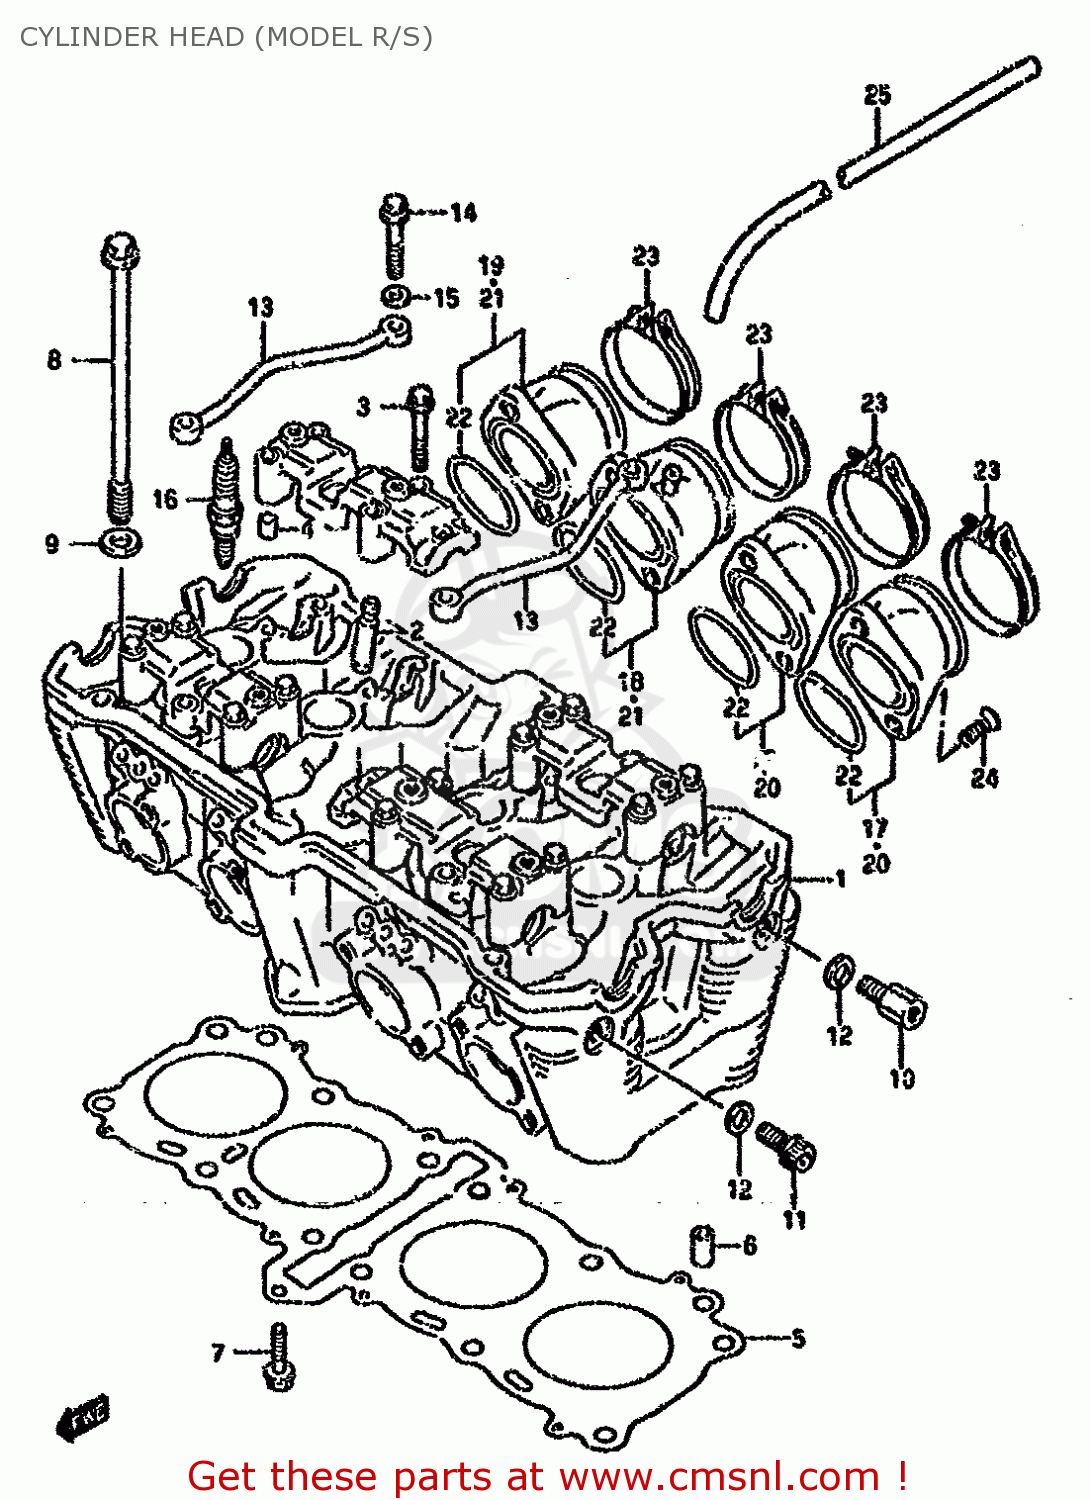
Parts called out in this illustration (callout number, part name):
1	HEAD ASSEMBLY,CYLINDER
2	GUIDE,VALVE
3	BOLT(6X45)
4	PIN(6.2X8X11)
5	GASKET,CYLINDER HEAD
6	PIN
7	BOLT
8	BOLT(10X160)
9	WASHER(10.5X19X2)
10	BOLT
11	BOLT
12	GASKET(8.2X14X1).6 (NAS)
13	PIPE,CYLINDER HEAD OIL
14	BOLT(6X39)
15	WASHER
16	PLUG,SPARK(CR8E)
17	PIPE ASSEMBLY,INTAKE
18	PIPE ASSEMBLY,INTAKE
19	PIPE ASSEMBLY,INTAKE
20	PIPE ASSEMBLY,INTAKE NO.1
21	PIPE ASSEMBLY,INTAKE NO.2
22	O RING(D:2.4,ID:44)
23	CLAMP
24	SCREW(6X16)
25	HOSE
